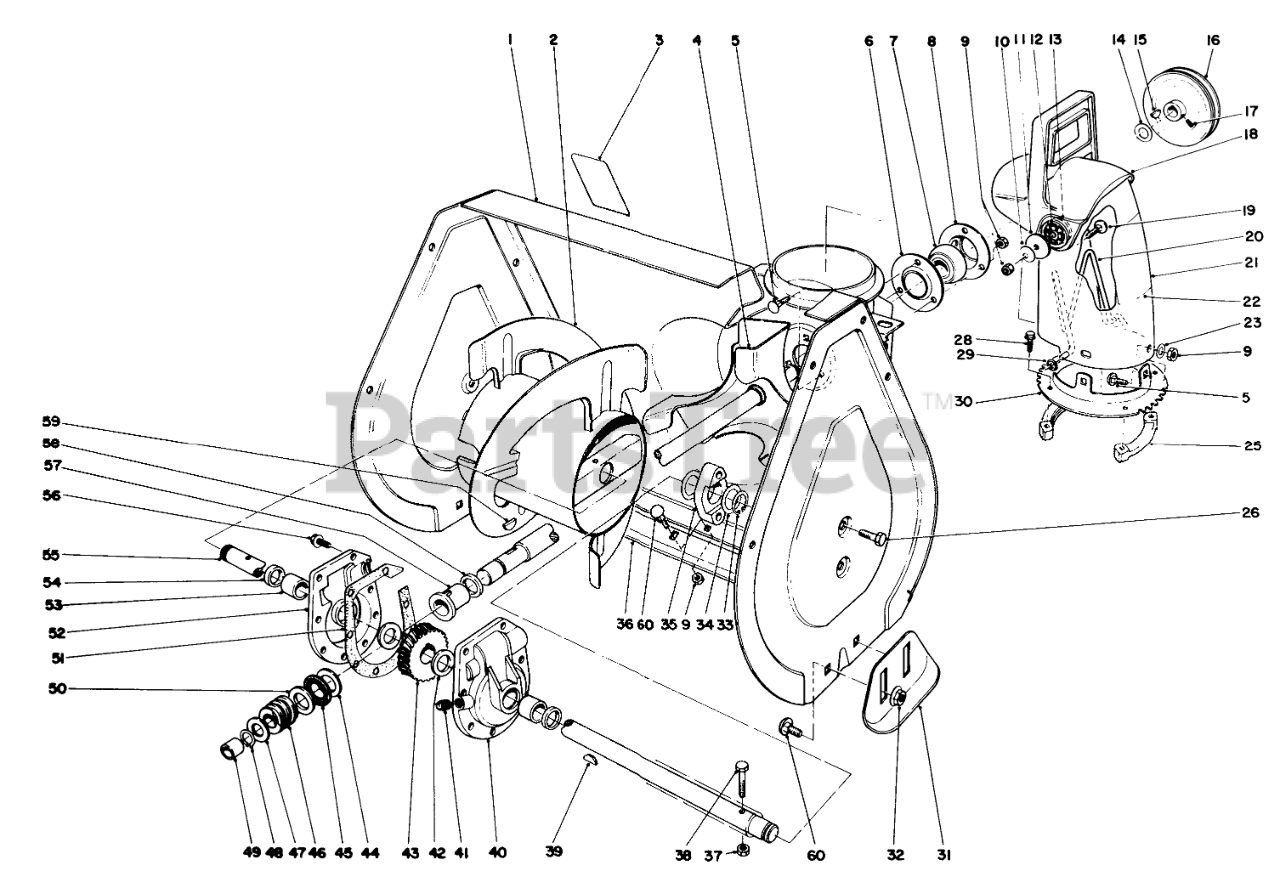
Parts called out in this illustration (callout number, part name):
1	Housing-Auger (Incl. Ref. #3 & 27)
2	Auger R.H.
3	DECAL-WARNING, AUGER
4	Shaft & Impeiler
5	SCREW-CARR
6	Flange Bearing-Front
7	BEARING-BALL
8	Flange Bearing-Rear
9	NUT-LOCK, NI
10	WASHER-BELLEVILLE
11	WASHER-FLAT
12	PLATE-FRICTION
13	WASHER-RUBBER
14	WASHER
15	KEY-WOODRUFF
16	PULLEY
17	SCREW-SET, SQH
18	CHUTE-DEFLECTOR
19	SCREW-CARR
20	WIRE-CHUTE
21	Chute Discharge (Incl. Ref. #22)(Model 38052)
21	Chute Discharge (Incl. Ref. #22)(Model 38052C)
22	Decal-Danger
22	DECAL-DANGER DISCH.
23	WASHER-PLAIN
25	RING-CHUTE, RETAINER
26	SCREW-HWHTF
28	SCREW-SPECIAL
29	NUT-PUSH
30	Chute Ring
31	Skid
32	NUT-HF
33	RING-RETAINING
34	WASHER
35	BEARING-AUGER
36	Blade-Scraper
37	NUT-LOCK, NI
38	SCREW-HH
39	KEY-WOODRUFF
40	Gear Case-L.H. (Incl. Ref. #53 & 54)
41	PLUG-PIPE, SQH
42	WASHER-THRUST
44	WASHER-THRUST
45	BEARING-THRUST
47	WASHER-THRUST
48	Ring-Snap
49	BUSHING
50	WASHER-THRUST
51	GASKET-CASE, GEAR
52	Gear Case-R.H. (Incl. Ref. #53 & 54)
53	BUSHING
54	SEAL-OIL
55	AUGER SHAFT
56	SCREW-TAPTITE
57	BUSHING-INPUT
58	RING-QUAD
59	KEY-WOODRUFF
60	BOLT-CARR
